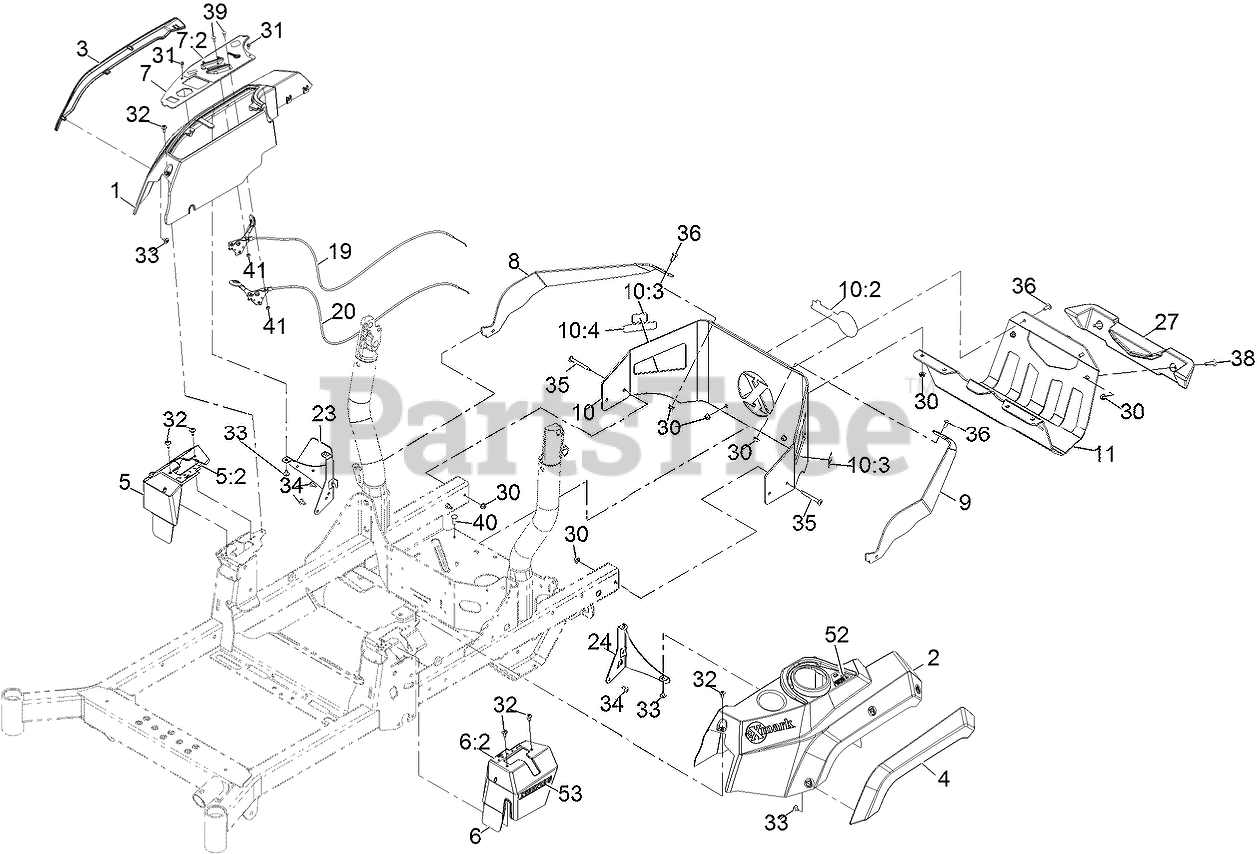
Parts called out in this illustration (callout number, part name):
1	CONSOLE-EXMARK, RH
2	CONSOLE, LH
3	FENDER-RH
4	FENDER-LH
5	COVER-CONTROL, MOTION (RH
5:2	Decal-Control, Motion (RH)
6	COVER-CONTROL, MOTION (LH
6:2	Decal-Control, Motion (LH)
7	ASM-CONTROL PANEL W/EXMARK DECAL
7:2	DECAL-CONTROL PANEL
8	SUPPORT-UPPER, RH
9	SUPPORT-UPPER, LH
10	REAR GUARD ASM
10:2	DECAL, EXMARK LOGO
10:3	DECAL-WARNING
10:4	DECAL-ARRESTOR, SPARK
11	Guard-Muffler [black]
19	CABLE-CONTROL, CHOKE
20	CABLE-CONTROL, THROTTLE
23	SUPPORT-CONSOLE, RH
24	BRACKET-CONSOLE, LH
30	NUT-HF, NI
31	SCREW-HWH
32	SCREW-SHOULDER
33	SCREW-TORX
34	SCREW-TORX
35	SCREW-TORX
36	SCREW-TORX
38	SCREW-TORX
39	BOLT-CARR
40	SCREW-CARR
41	NUT-LOCK, NI
52	DECAL-FILL, FUEL
53	DECAL-X-SERIES
